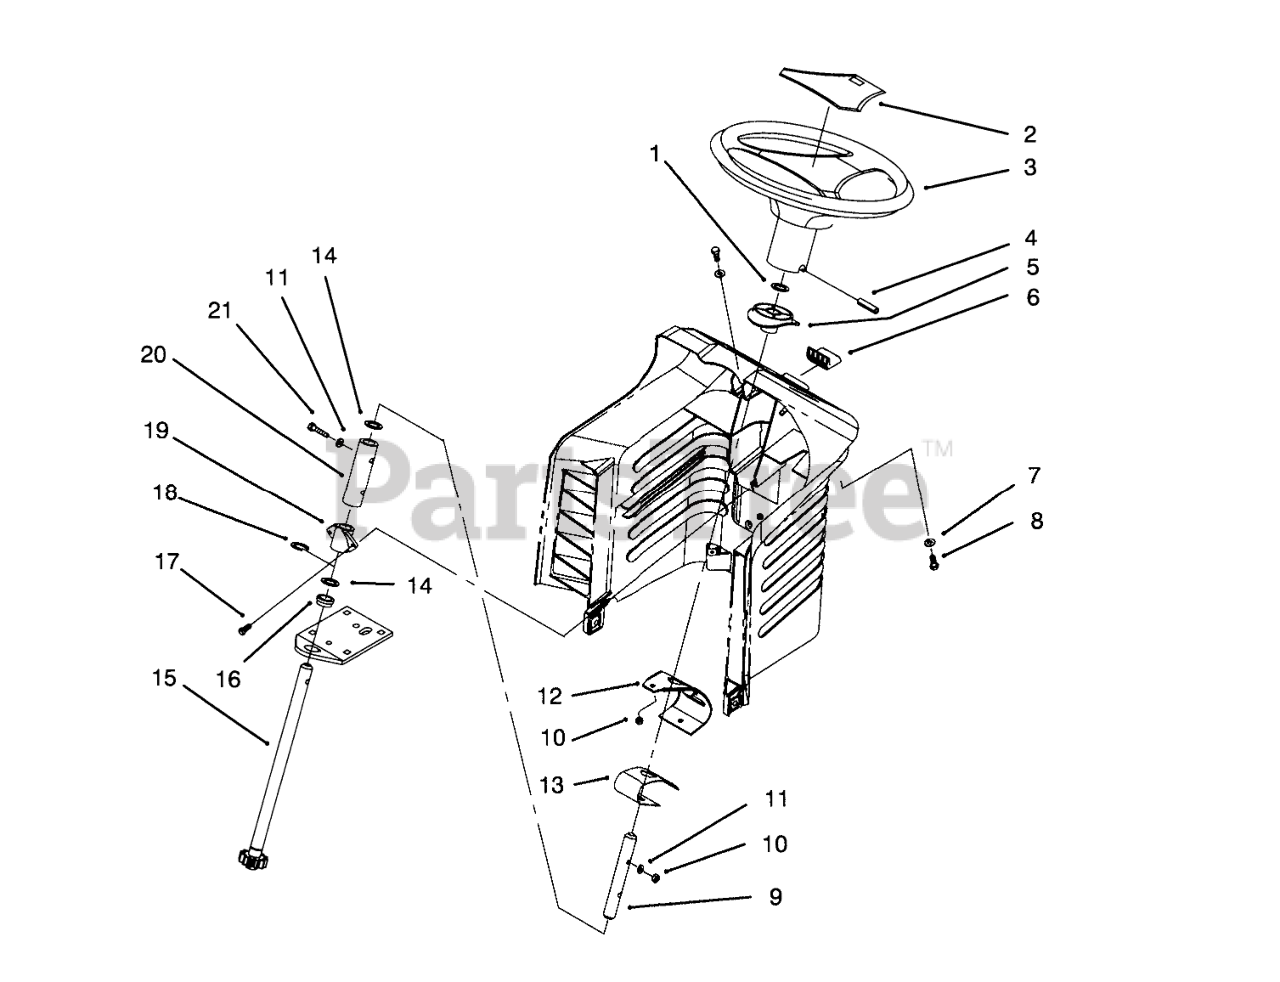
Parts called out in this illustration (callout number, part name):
1	PUSH-ON RETAINING RING
2	COVER-WHEEL
3	Wheel-Steering (Incl. Ref. #2)
4	PIN-ROLL
5	BUSHING-SLIDING
6	RELEASE BUTTON
7	WASHER-FLAT
8	SCREW-HH
9	UPPER STEERING SHAFT
10	NUT-LOCK, NI
11	WASHER
12	BACKUP BRACKET
13	SPRING LEAF
14	WASHER-THRUST
15	SHORT STRG SHAFT WA
16	BEARING-FLANGE
17	SCREW-SPECIAL
18	E-RING
19	BUSHING STATIONARY
20	COUPLING, STEERING
21	SCREW-HH
